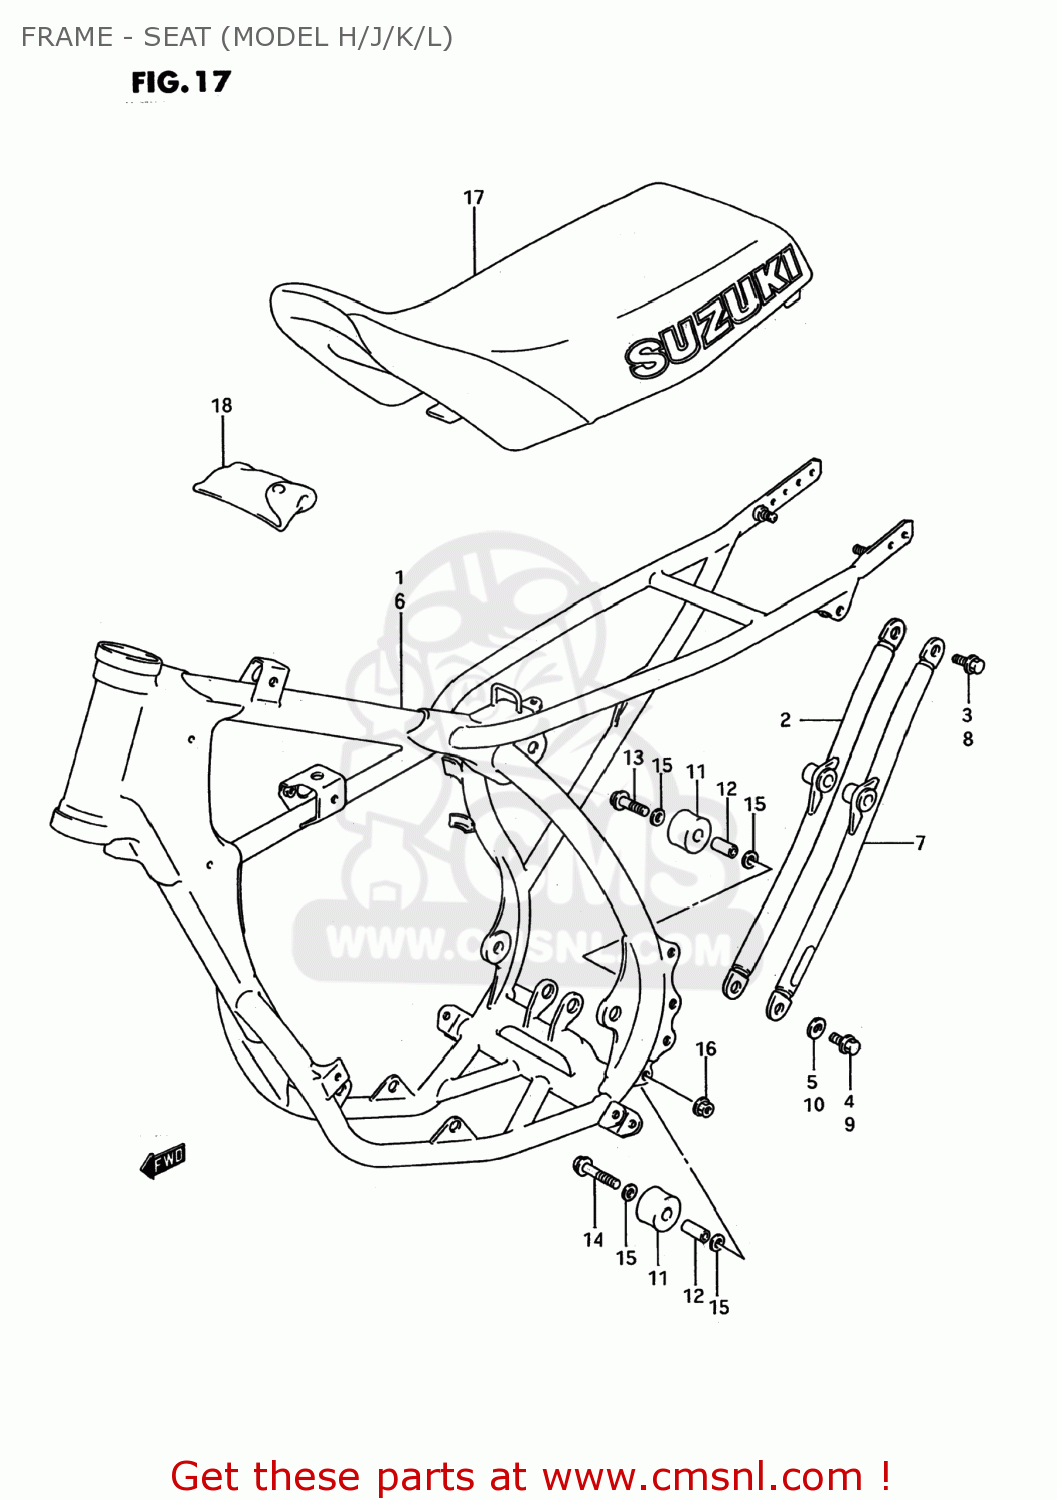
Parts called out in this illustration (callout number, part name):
1	FRAME
2	TUBE COMP,FRAME SIDE,LEFT
3	BOLT
4	BOLT
5	WASHER
6	FRAME
7	TUBE,FRAME SIDE,LEFT
8	BOLT
9	BOLT
10	WASHER
11	ROLLER,CHAIN CONTROL
12	SPACER(8.6X12X25.5)
13	BOLT(8X41)
14	BOLT
15	WASHER
16	NUT
17	SEAT ASSEMBLY
18	TOOL SET
